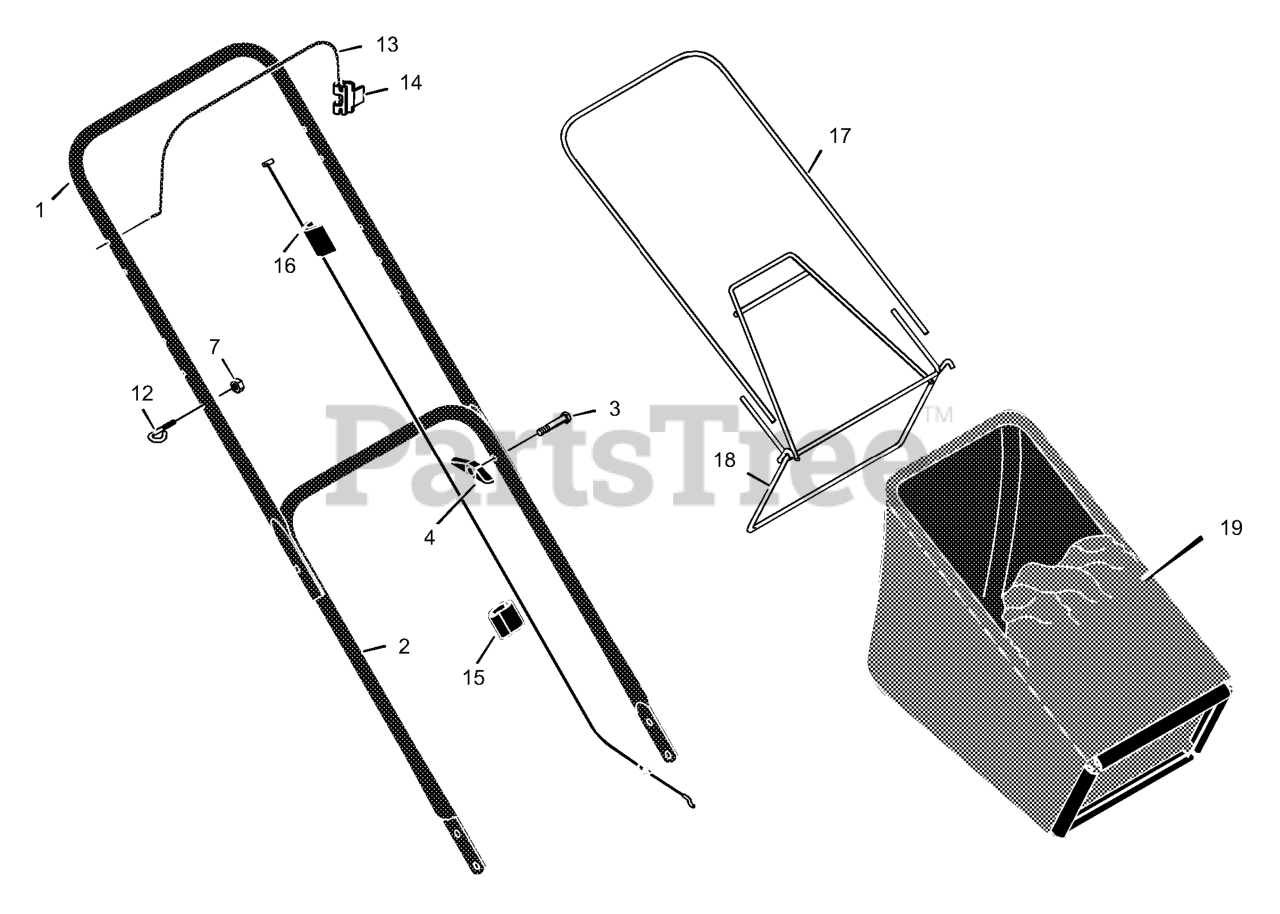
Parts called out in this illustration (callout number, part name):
1	Handle, Upper (Black)
2	Handle, Lower (Black)
4	Knob, Plastic
7	Locknut
12	Guide, Rope
13	Engine Stop Lever
14	Bracket, Stop Lever
15	Fastener, Double Cable
16	Engine Stop Cable
17	Frame, Top
18	Frame Assembly
19	Bag, Cloth - Black
